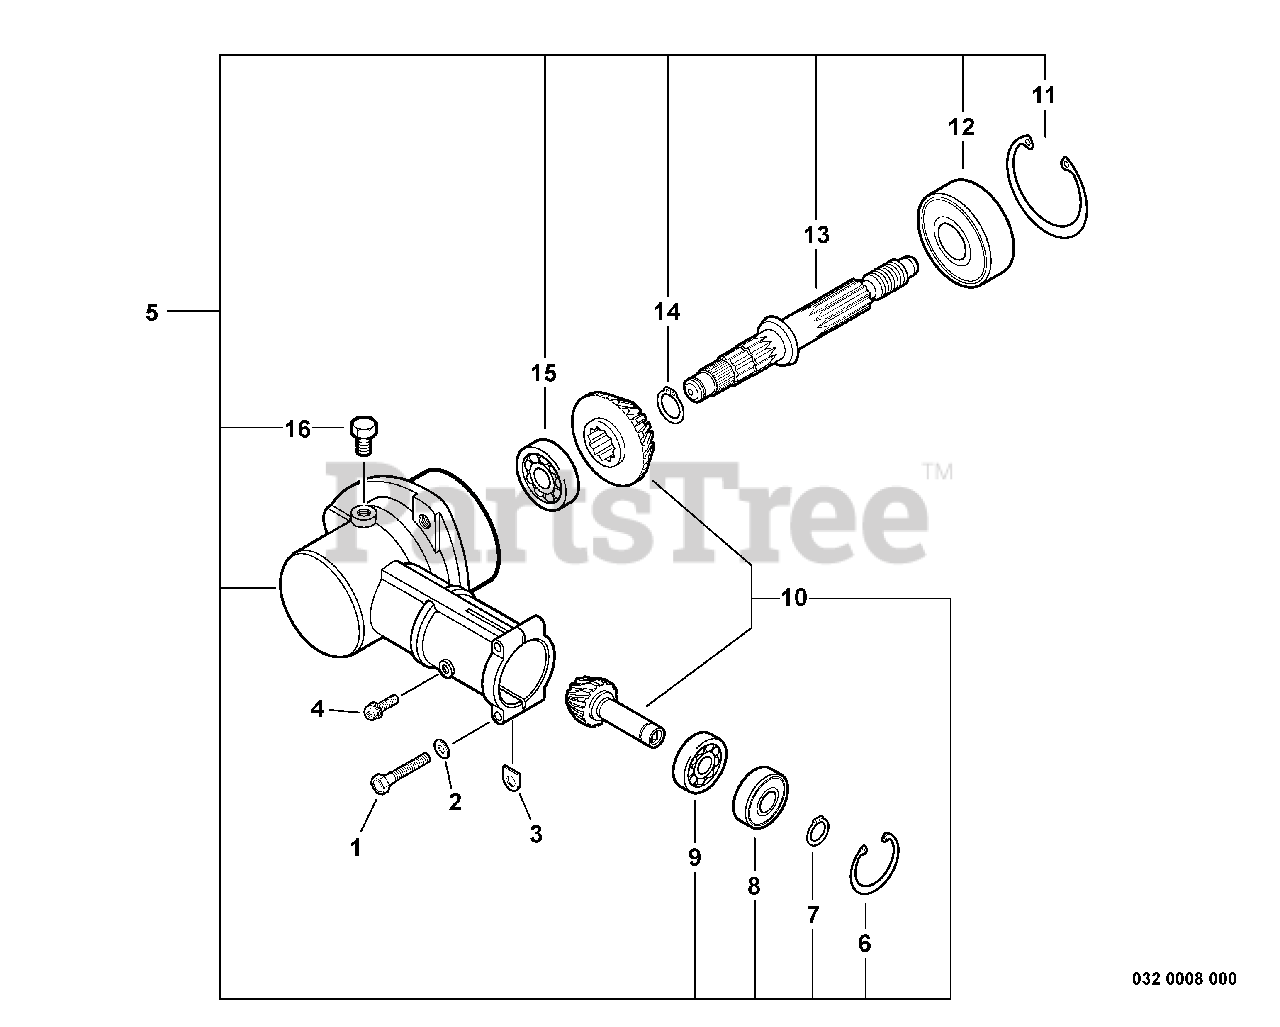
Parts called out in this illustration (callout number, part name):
1	BOLT 5×30
2	WASHER, FLAT 5.5×10×0.8
4	SCREW 5×12
5	GEAR CASE ASSY
6	RING, SNAP Ø22
7	RING, SNAP Ø10
8	BEARING, BALL 6900Z
9	BEARING, BALL 6900
10	GEAR SET
11	RING, SNAP Ø42
12	BEARING, BALL 6302
13	SHAFT, GEAR
14	RING, SNAP Ø12
15	BEARING, BALL 629
16	BOLT M8×8
